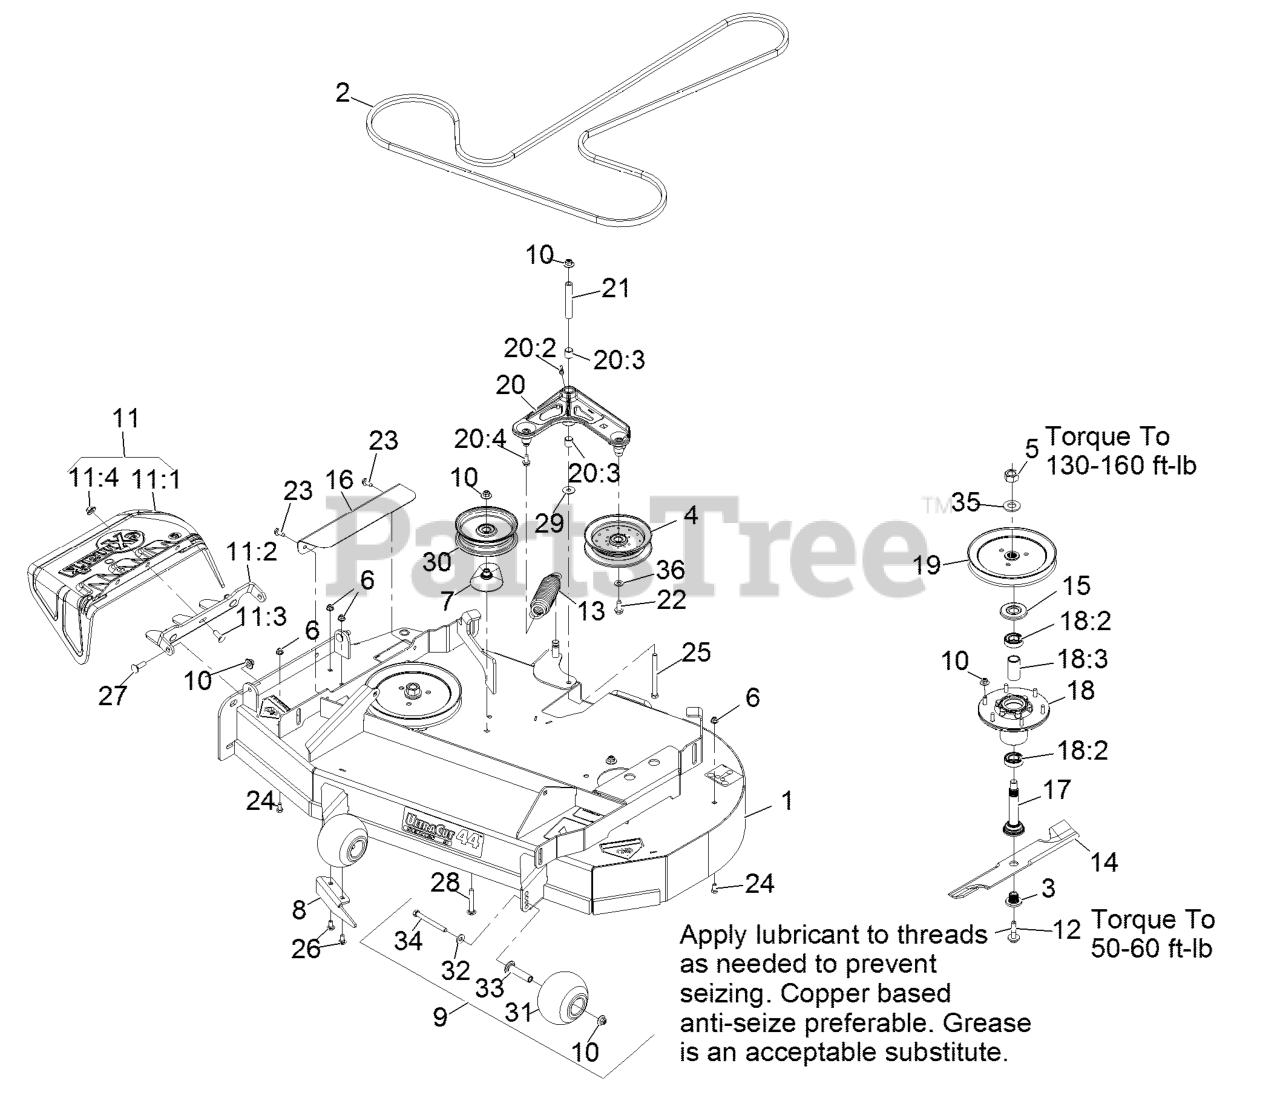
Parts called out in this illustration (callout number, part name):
1	ASM-DECK W/DECALS 44
2	BELT - V, B
3	BUSHING,SPLINED
5	NUT-HEX
6	NUT-HF, NI
7	SPACER-PULLEY
8	BAFFLE-DISCHARGE
9	KIT, ANTI-SCALP ROLLER
10	Nut-Nyloc 3/8-16 Flg
11	ASM,DISCHARGE CHUTE
11:1	CHUTE,DISCHARGE
11:2	BRACKET,DISCHARGE CHUTE
11:3	SCREW-CARR
11:4	Nut-Nyloc 3/8-16 Flg
12	SCREW,SEMS 1/2-20 X 2.19
13	SPRING-EXTENSION
14	Blade-Mulch, 22.25
14	Blade-Notched, 22.25
15	GUARD,BEARING TOP .989
16	COVER,BELT
17	ASM-SPINDLE AND SEAL
18	ASM-CUTTER HSG WITH BEARINGS
18:2	BEARING-BALL
18:3	SPACER-BEARING
19	SHEAVE-BLADE DRIVE, 8.40
20	IDLER ARM ASM
20:2	FITTING-GREASE, 90 DEG
20:3	SLEEVE-BEARING
20:4	SCREW-THD ROLL, HWH
21	BUSHING
22	SCREW-FORMING, THREAD
23	Screw-HWH 5/16-18 X 3/4 Tf
24	SCREW-HH
25	SCREW-HH
26	BOLT-CARR
27	BOLT-CARR
28	SCREW-CARR
30	IDLER-PULLEY, FLAT
31	ROLLER-SCALP, ANTI
32	WASHER-BELLEVILLE
33	AXLE, ROLLER
34	SCREW-HH 3/8-16 X 3 3/4 GR 8
36	WASHER-FLAT
